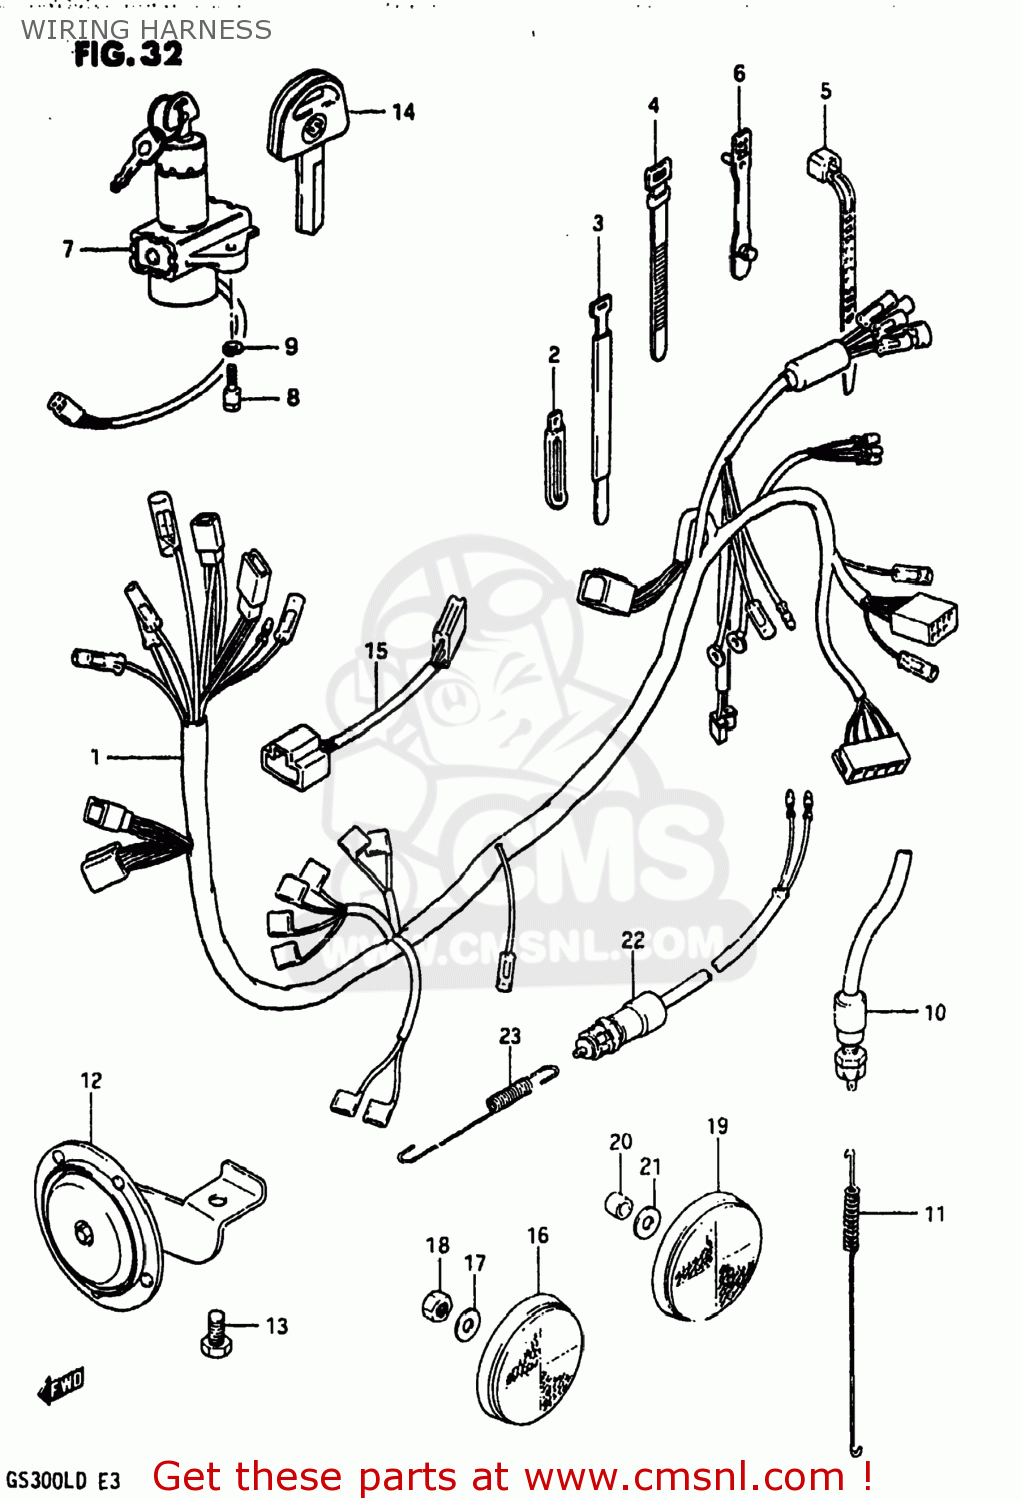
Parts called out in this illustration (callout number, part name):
1	HARNESS,WIRING
2	CLAMP
3	CLAMP
4	CLAMP(L:120)
5	CLAMP(L:95)
6	CLAMP,L:88
7	IGNITION SWITCH ASSEMBLY
8	BOLT
9	LOCK WASHER
10	SWITCH ASSEMBLY,STOP LAMP
11	SPRING
12	HORN ASSEMBLY
13	BOLT 8X12
14	KEY,BLANK
15	LEAD WIRE,HEADLAMP
16	REFLEX REFLECTOR,RR
17	WASHER
18	NUT
19	REFLECTOR,REFLEX
20	SPACER (5.5X9.5X6.5)
21	WASHER
22	SWITCH ASSEMBLY,SIDE STAND
23	SPRING
